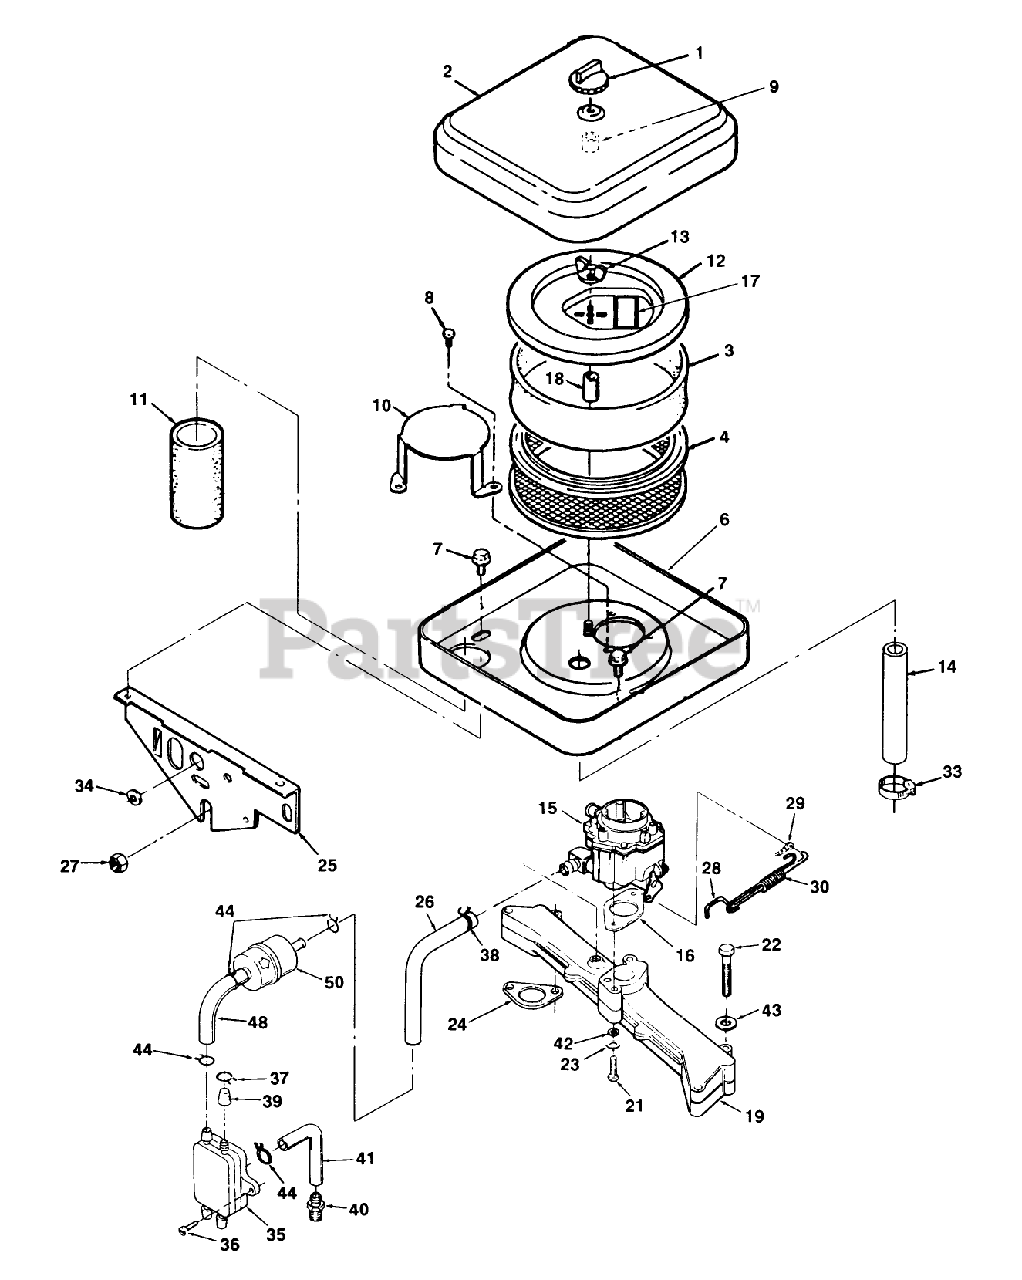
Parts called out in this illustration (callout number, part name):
3	WRAPPER-AIR CLEANER ELEMENT
4	ELEMENT-AIR CLEANER
7	Screw-Hex Washer Hd
11	TUBE-AIR INTAKE
14	HOSE-RUBBER, BREATHER
16	GASKET-CARBURETOR
17	DECAL-PERIODIC MAINTENANCE
18	SPACER-AIR CLEANER STUD
19	MANIFOLD - INTAKE
23	WASHER-FLAT
24	GASKET-MANIFOLD TO BLOCK
25	SUPPORT-AIR CLEANER
33	CLAMP-HOSE, BREATHER
34	GROMMET
39	CAP-FUEL OUTLET
41	HOSE-VACUUM
42	WASHER-FLAT
43	WASHER-FLAT
44	CLAMP-HOSE
50	FUEL FILTER
